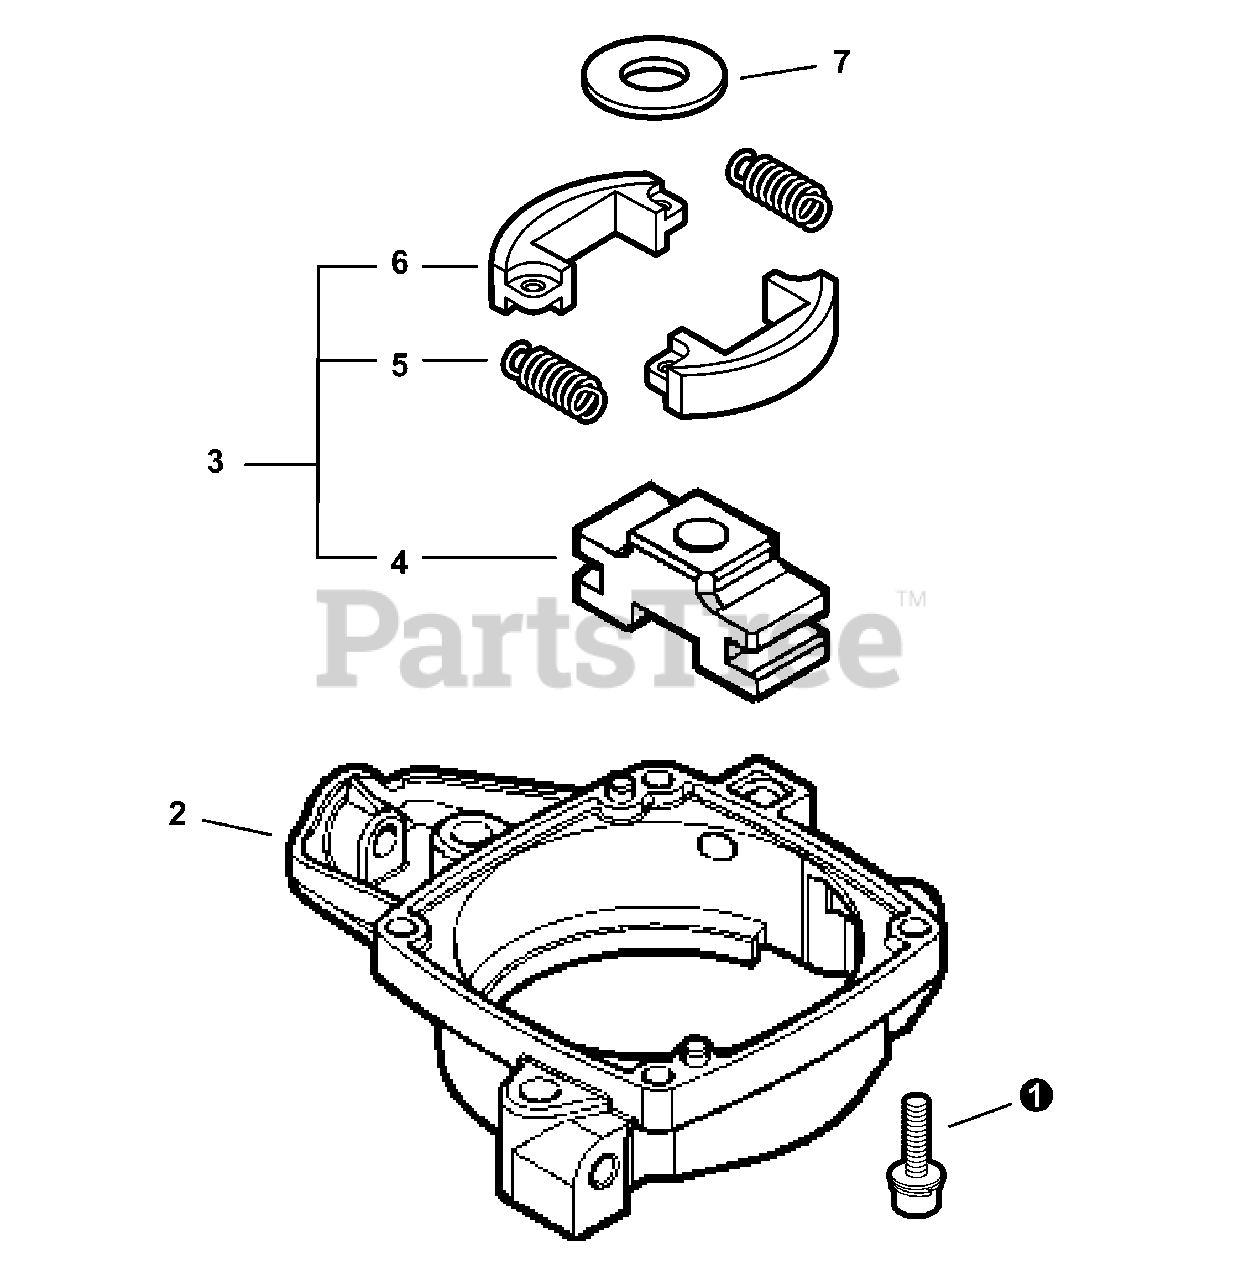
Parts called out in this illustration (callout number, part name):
1	BOLT 4×16
2	CASE, CLUTCH
3	CLUTCH ASSY
4	HUB, CLUTCH
5	SPRING, CLUTCH
6	SHOE, CLUTCH
7	WASHER 8
